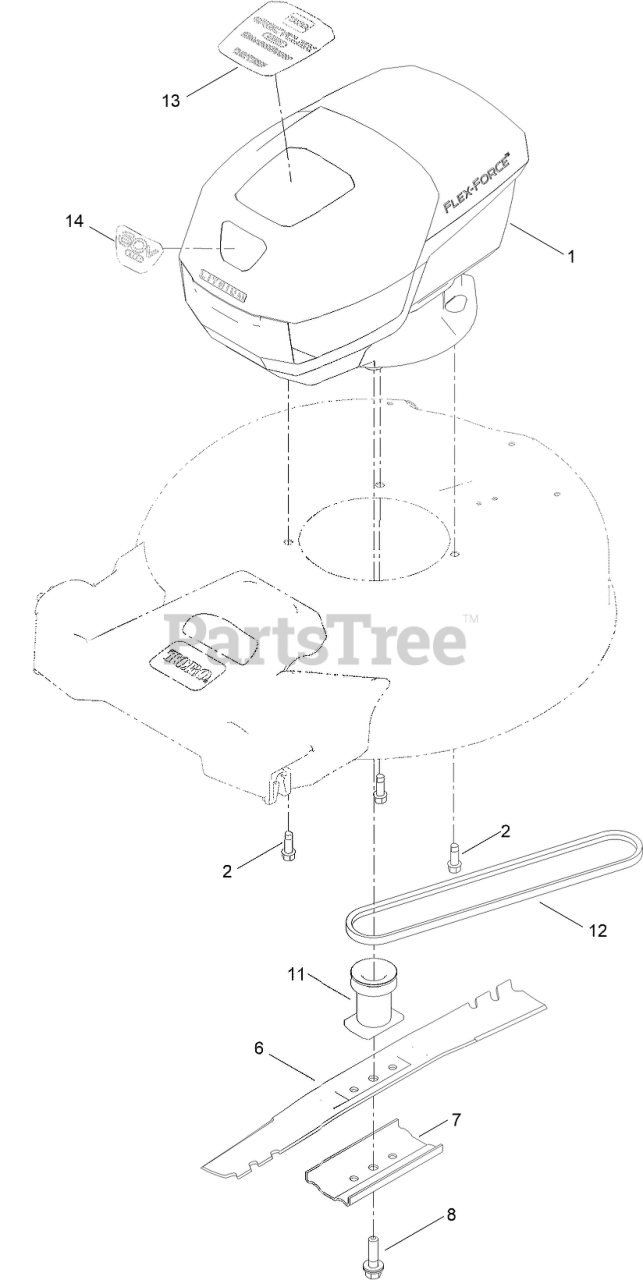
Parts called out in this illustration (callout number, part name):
1	MOTOR MODULE
2	SCREW-TAPTITE
6	BLADE-21IN (MULCH, HS)
7	SUPPORT-BLADE
8	BOLT-BLADE
11	DRIVER-BLADE
12	BELT-V
13	DECAL-eS52VST, TOP
14	DECAL - 60V, FRONT
